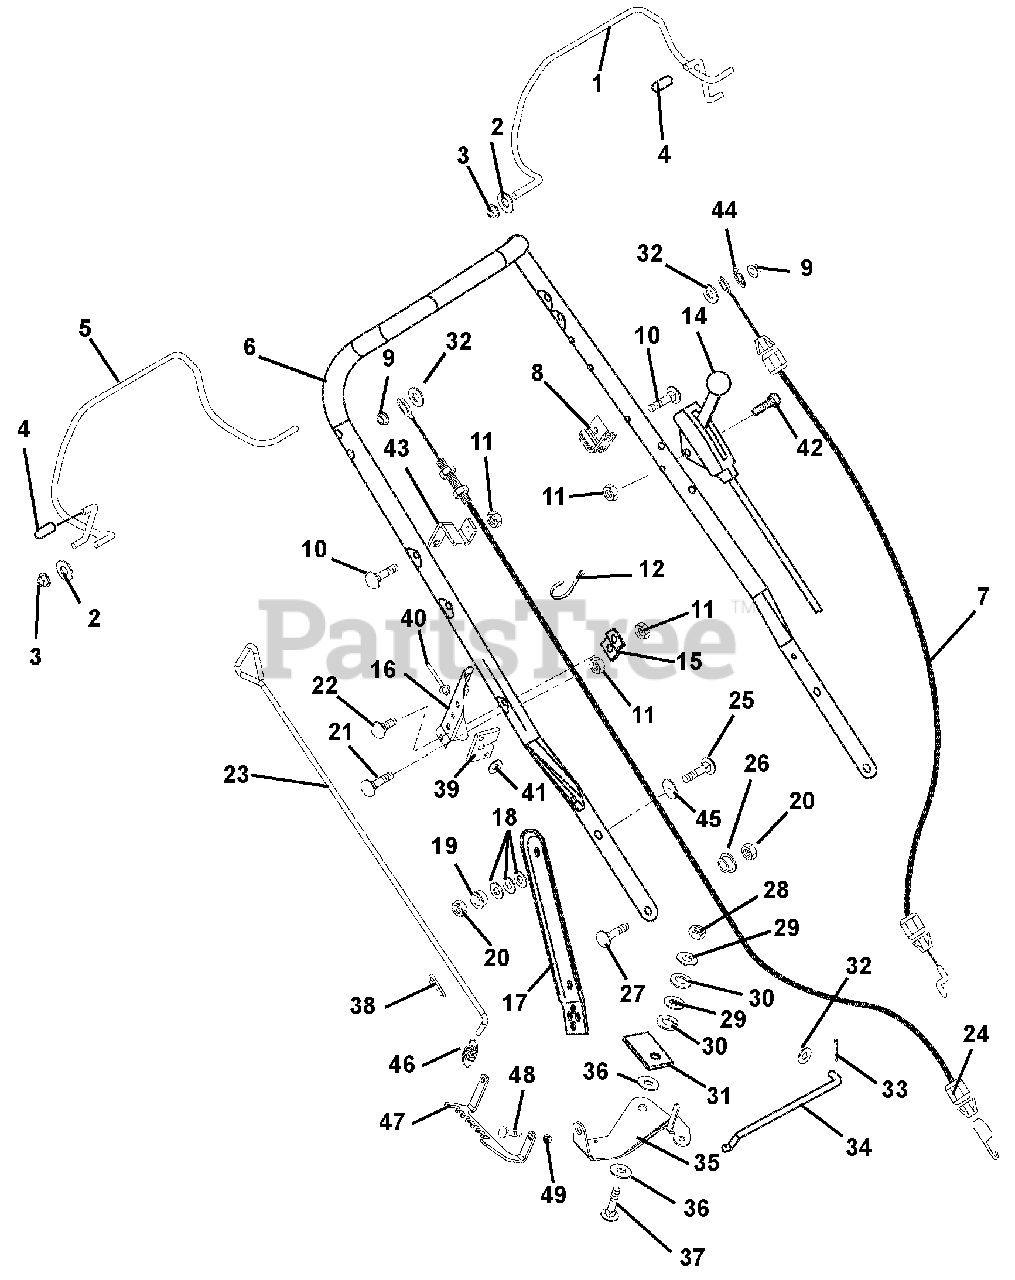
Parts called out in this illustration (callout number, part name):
1	BAIL, WBLM ENGINE
2	@WSHR-FL-STL.344X.688X.065YWZC
3	BSHG-FLG .325X.444X.440X.560
4	CAP, VINYL, .25 ID
5	BAIL, WBLM TRACTION
6	HANDLE BAR, CLASSIC LM21
7	CABLE, WBLM ENGINE
7	CABLE, ENGINE - ADJUSTABLE
8	BRKT, ENGINE CABLE ANCHOR
9	PUSH NUT, .25
10	BLT-RDHDXLSQNK.25-20X1.25 G5ZC
11	@NUT-LK-CTR .25-20 YWZC
12	@NUT-LK-CTR .25-20 YWZC
13	CABLE TIE LG 5-1/2
14	CABLE, LOCKOUT CONTROL
15	BRACE, SPEED CONTROL
16	BRKT, SPD CONTROL SLOTTED
17	LINK, HANDLEBAR ADJUSTMENT LH
17	LINK, HANDLEBAR ADJUSTMENT RH
18	WASHER, BELLEVILLE YWZC
19	BSHG-FLG .325X.500X.513X.875
20	@NUT-LK-CTR .31-18 YWZC
21	BLT-RDHDSQNK .25-20X1.38 GR5YZ
22	@BLT-RDHDSQNK .25-20X.50 G5YZ
23	SPEED CONTROL ROD
24	CABLE, WBLM TRACTION
25	@BLT-RDHDSQNK .31-18X1.00 G5YZ
26	BSHG, FLG .325X.499X.26X.88
27	@BLT-RDHDSQNK .31-18X.75 G5YZ
28	@NUT-LK-CTR .38-16 YWZC
29	@WSHR-FL-STL.406X.812X.065 YWZ
30	WSHR-LK .375X.115 HVY YWZC
31	PRESSURE FLANGE
32	@WSHR-FL-STL.281X.62X.065 YWZC
33	@PIN-CTR .06X.50 EXTPRSQCT YWZ
34	SHIFT LINK
35	CRANK, SPEED CONTROL BELL
36	FRICTION WASHER
37	@BLT-RHDSSQNK .38-16X1.25 G5YZ
38	PIN-HAIR INT .08X.18X1.18 YWZC
39	PAD, RUBBER SUPPORT
40	RVT .187X.575 DOME AL BLACK
41	@WSHR-FL-STL.219X.50X.049 YWZC
42	BLT-RDHDXLSQNK .25-20X2.0 G5YZ
43	BRKT, TRACTION CABLE ANCHOR
44	RG-RTNG-EXT .250X.010
45	WSHR-FL-STL .505X.880X.072 YWZ
46	SPRING, EXTENSION
47	BRKT, SPD SELECTION
48	@BLT-RDHDSQNK .25-20X.50 G5YZ
49	@NUT-LK-CTR .25-20 YWZC
